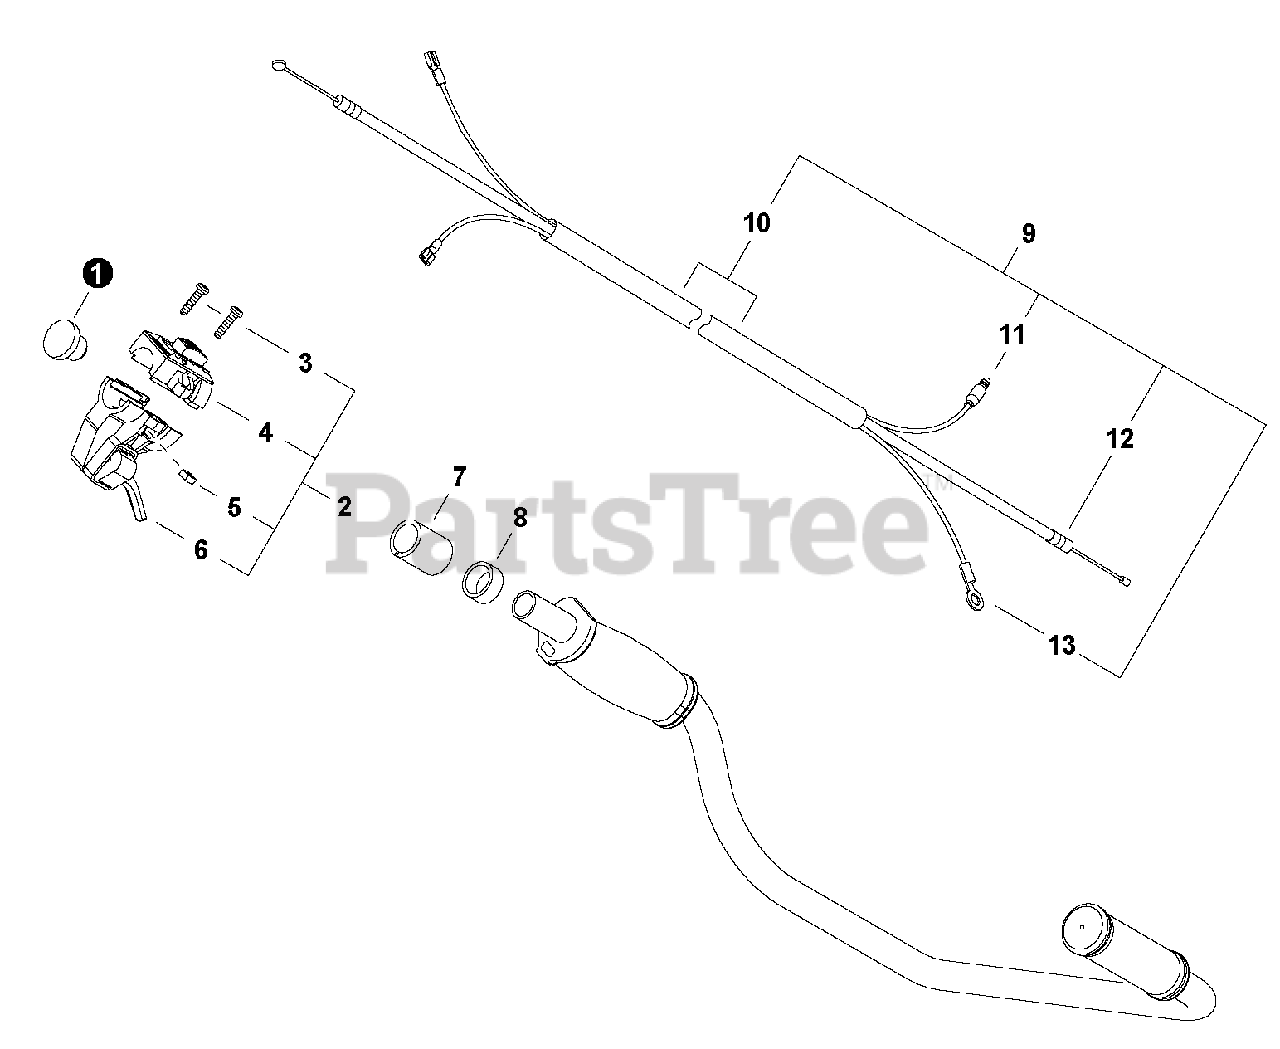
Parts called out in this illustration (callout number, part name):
2	THROTTLE CONTROL KIT
4	SWITCH ASSY, ON-OFF
5	NUT
6	BODY, THROTTLE CONTROL
9	CABLE ASSY, THROTTLE
11	LEAD - RED
12	CABLE, THROTTLE
13	LEAD - BLACK
